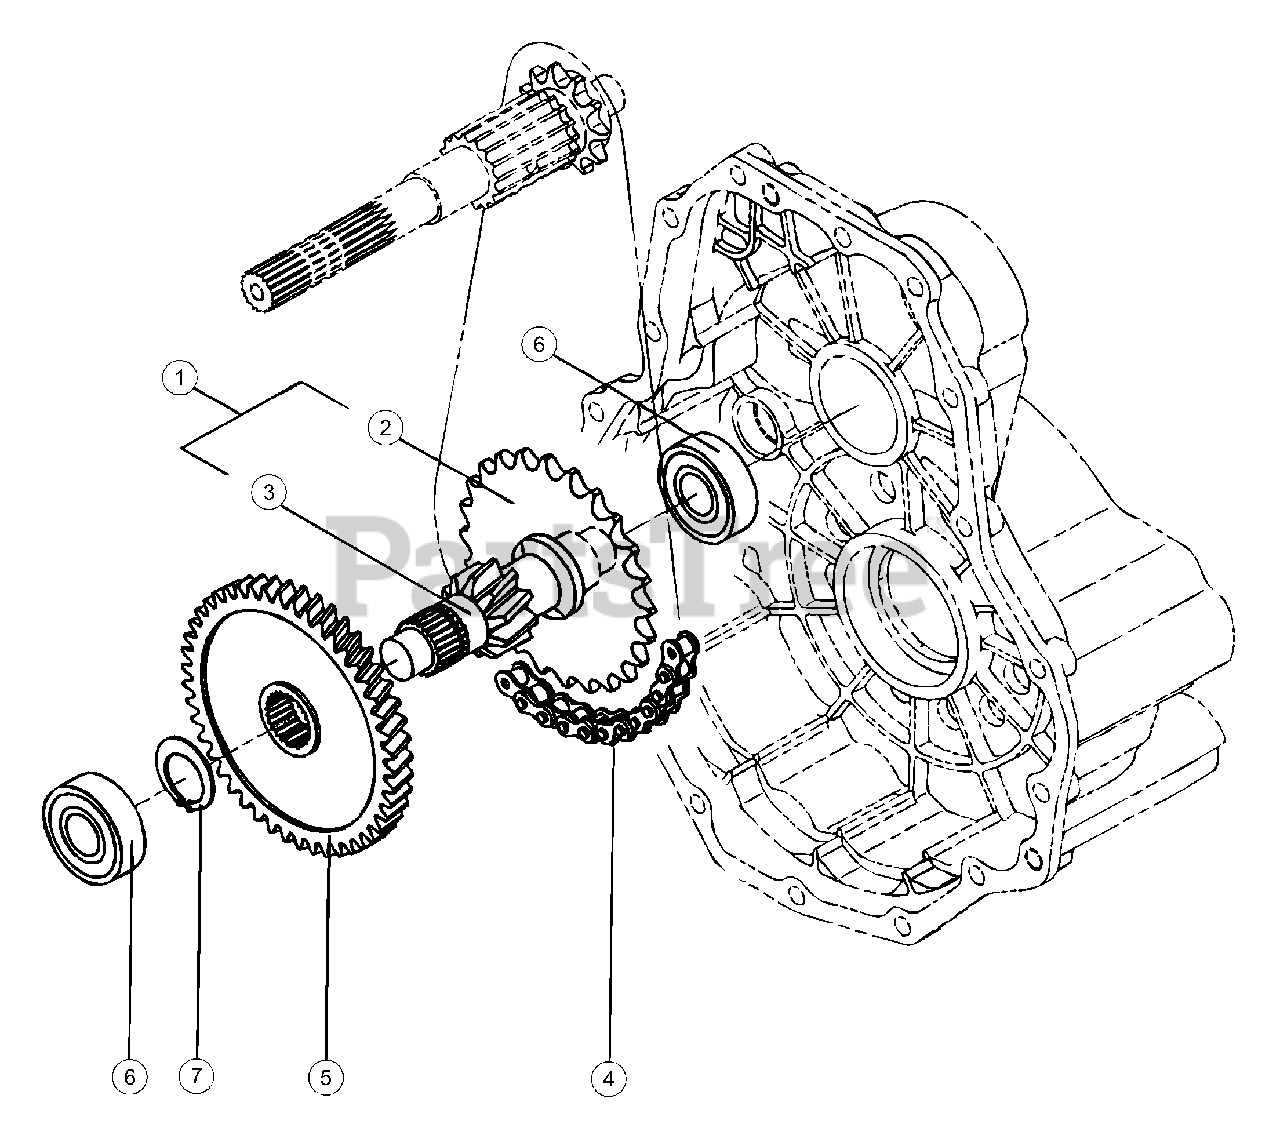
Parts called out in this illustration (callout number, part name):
1	Reduction Shaft Assembly
2	Sprocket, 27
3	Shaft, Reduction
4	Chain, 40 x 34
5	Gear, 46H, Reduction
6	Bearing, 6204R, SH2
7	Ring, 26
